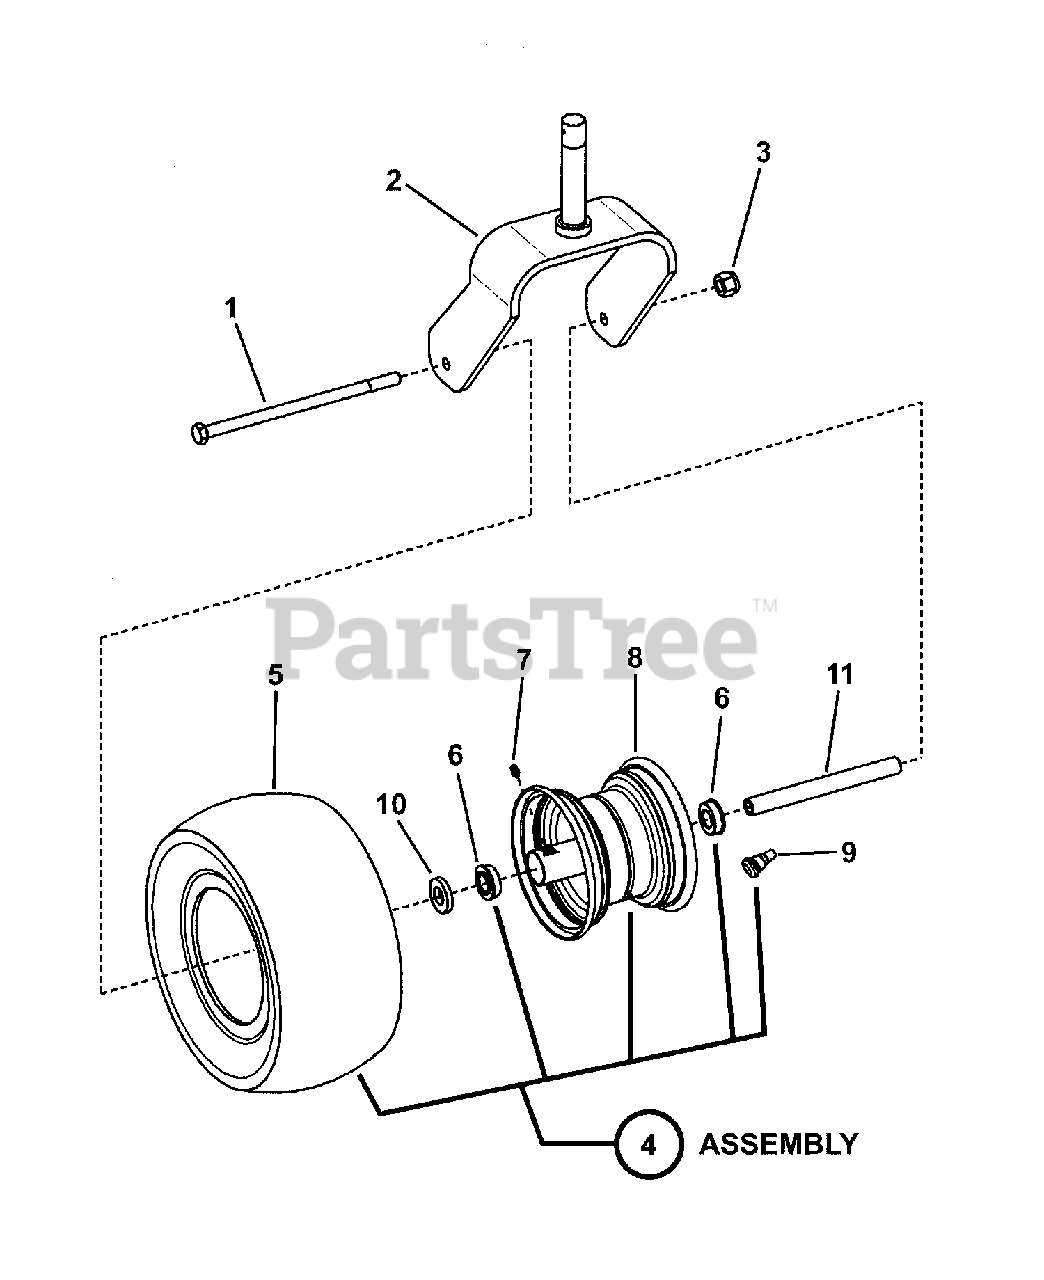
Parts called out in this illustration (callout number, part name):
1	SCREW, 1/2-13 x 9-1/2" Hex Head Cap, GR 5
2	WELDMENT, Caster Yoke, 7-1/4" Wide
3	NUT, 1/2-13 Hex Nyloc
4	ASSEMBLY, Wheel & Tire
4	ASSY, Wheel & Tire, 13 x 6.50-6 (Incl. items 5A & 8A)
5	TIRE, 13 x 6-6.5 4 Ply
6	BALL BEARING, Heim .750
7	FITTING, 1/4-28 Lube
8	WELDMENT, Front Wheel Rim
9	AIR VALVE STEM & Cap
10	SPACER
11	SPACER, Bearing, 7.29" Long
